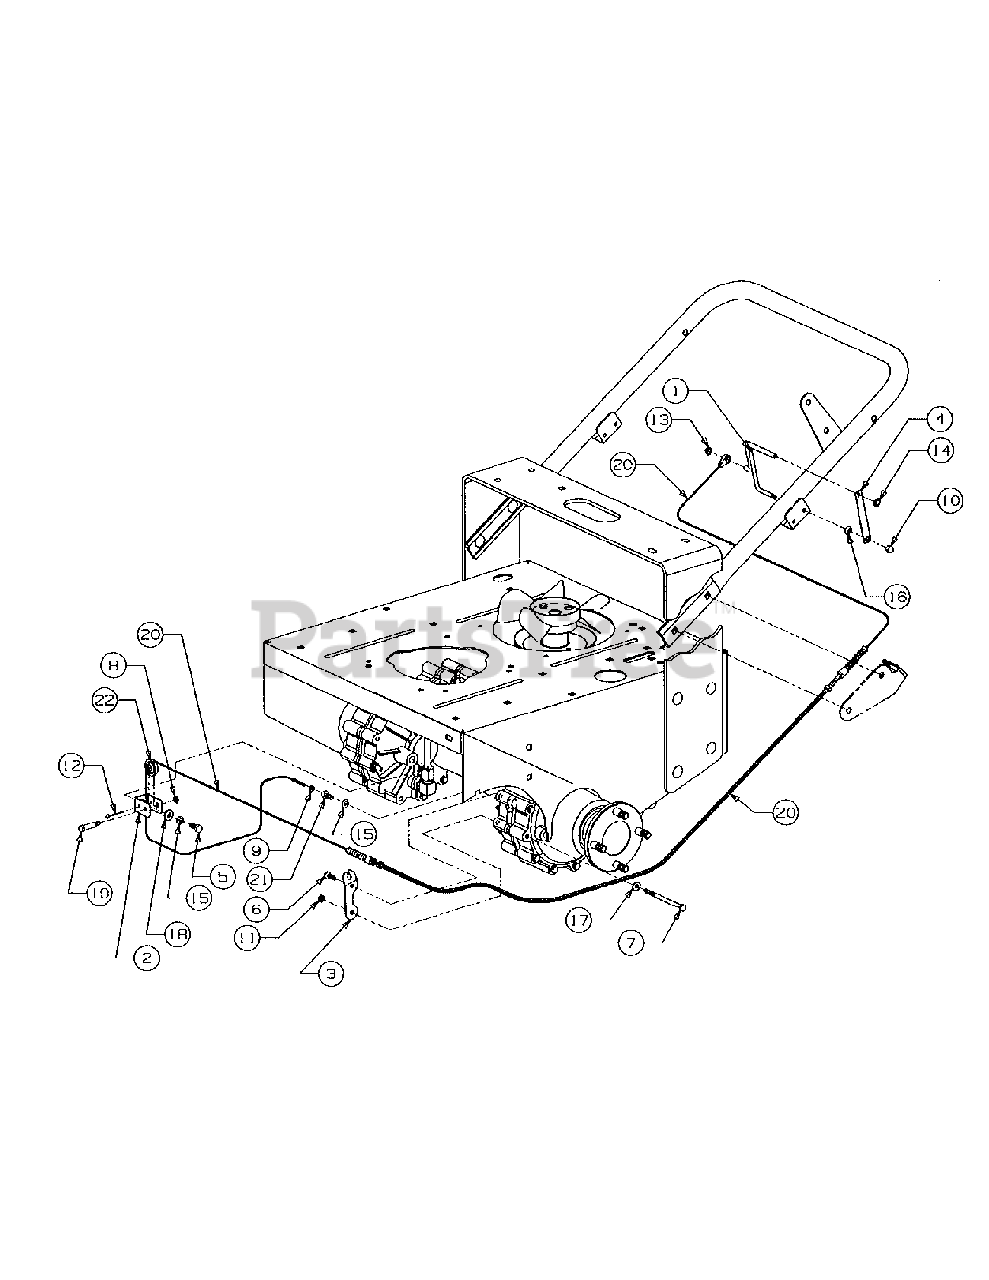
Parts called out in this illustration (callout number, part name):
1	Lever, Drive Wheel Release
2	Bracket, Pulley Mtg
3	Plate, Release Cable Mtg
4	Plate, Retainer
4	Graphic, Transaxle Release
5	Screw, Hex Cap 5/16-24 x .75 Gr 5
6	Screw, Hex Wash Hd Tapp, 1/4-20 x .75
7	Screw, Hex Cap, 1/4-20 x 4.0
8	Nut, Hex Top Lock, 1/4-20
9	Nut, Hex #10-32
10	Nut, Hex Lock Stop, 1/4-28
11	Nut, Hex Top Lock, 1/4-20 Gr 5
12	Pin, Cotter, 5/32 Dia x 1.25
13	Nut, Cap Speed.312 x Stud
14	Nut, Push-On Speed, 5/16
15	Washer, Lock 5/16
16	Washer, Spring
17	Washer, Flat .25 x .62
18	Washer, Flat, .312 x .750 x .119 Thk
19	Bolt, Pulley
20	Cable, Drive Wheel Release
21	Bolt, Cable Adapter
22	Pulley Cable
